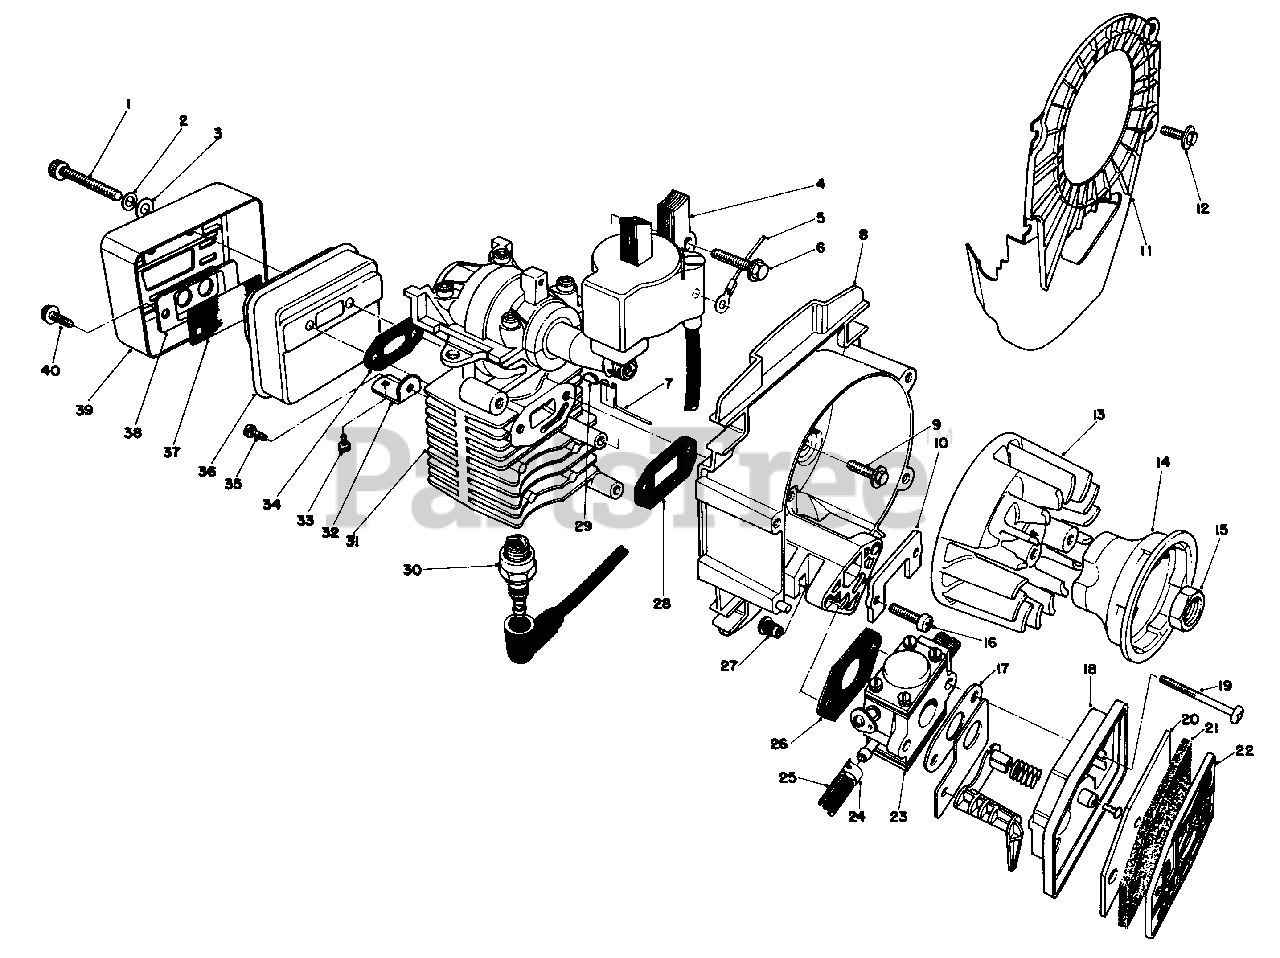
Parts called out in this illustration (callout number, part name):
1	Screw Muffler
2	Lockwasher
3	Flatwasher
4	CDI Module
5	Wire, Ground/Switch
6	Screw CDI
7	Wire, Coil/Switch
8	Backing Plate Assembly (Incl. Ref. #31)
9	Screw, Backing Plate
10	Plate, Stress
11	Cooling Shroud
12	Screw, Shroud
13	Flywheel
14	Cup, Starter
15	Nut, Flywheel
16	Screw, Intake
17	Gasket, Choke
18	Choke & Spitback Cup Assembly
19	Screw, Carburetor
20	Filter, Felt
21	Filter, Foam
22	Cover, Filter
23	Carburetor
24	Clamp, Fuel Line
25	Hose, Fuel Line
26	Gasket, Carburetor
27	Insert Threaded
28	Gasket, Intake
29	Key Flywheel
30	Spark Plug
31	Short Block
32	Tab, Heat Shield
33	Screw, Heat Shield/Tab
34	Gasket, Exhaust
35	Screw, Tab Cylinder
36	Muffler Assembly (Incl. Ref. #37,38 & 40)
37	Screen, Spark Arrestor
38	Plate, Muffler Outlet
39	Heat Shield, Muffler
40	Screw, Outlet Plate
